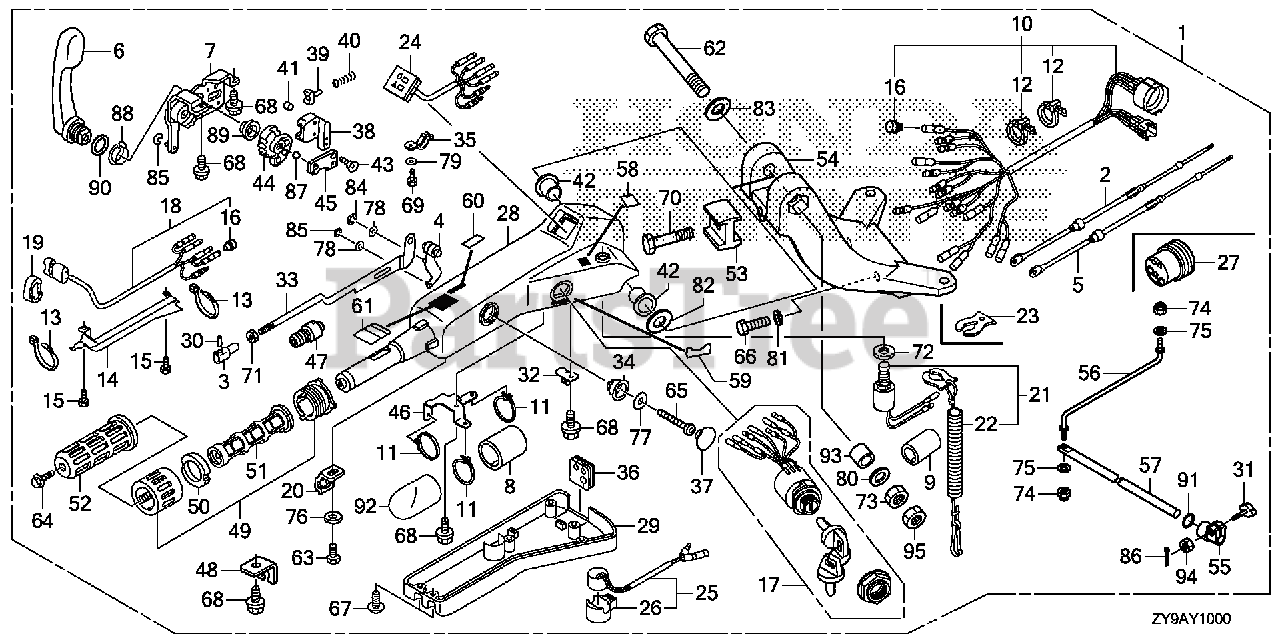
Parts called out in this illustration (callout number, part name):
1	HANDLEBAR KIT *NHB14M* (AQUA MARINE SILVER METALLIC)
2	CABLE, THROTTLE
3	PIVOT, THROTTLE CABLE
4	ARM, THROTTLE
5	CABLE, SHIFT
6	LEVER, SHIFT
7	FRAME ASSY., SHIFT
8	TUBE (38.1X40)
9	TUBE
10	CABLE ASSY., LONG HANDLE (A)
11	BAND (CONVEX CV-150)
12	BAND (CONVEX CV-200)
13	BAND (CONVEX)
14	COVER, WIRE
15	SCREW
16	PLUG, CONNECTOR (INNER)
17	SWITCH ASSY., COMBINATION
18	SWITCH ASSY., POWER TILT
19	GROMMET
20	HOLDER, SWITCH
21	SWITCH ASSY., EMERGENCY STOP
22	WIRE, EMERGENCY
23	CLIP, EMERGENCY LOCK
24	LAMP ASSY., INDICATOR
25	BUZZER ASSY., WARNING
26	SUSPENSION, WARNING BUZZER
27	GROMMET, HANDLEBAR CABLE
28	HOUSING *NHB14M* (AQUA MARINE SILVER METALLIC)
29	COVER, HANDLEBAR (LOWER)
30	PIN, THROTTLE CABLE
31	BOLT, FRICTION
32	BRACKET, CABLE
33	PLATE ASSY., LOCK
34	STOPPER
35	PLATE, GUIDE
36	GROMMET
37	CAP
38	GUIDE, SPRING
39	ACTUATOR
40	SPRING, COIL
41	ROLLER
42	BUSH, HANDLEBAR
43	SCREW (M5X14)
44	GEAR, SHIFT
45	PLATE, BALL GUIDE
46	BRACKET
47	ROD, GROMMET
48	CLAMP, BRACKET
49	GRIP ASSY., THROTTLE FRICTION
50	PAD, THROTTLE FRICTION
51	PIPE, GRIP
52	RUBBER, GRIP
53	BLOCK, HEIGHT ADJUSTER
54	BRACKET B, STEERING *NHB14M* (AQUA MARINE SILVER METALLIC)
55	BLOCK, STEERING FRICTION
56	ROD, STEERING FRICTION
57	SHAFT, STEERING FRICTION
58	MARK, EMERGENCY SWITCH INDICATION (EU)
59	MARK, STARTER (ENGLISH)
60	MARK, CHANGE
61	MARK, THROTTLE (ENGLISH)
62	BOLT, HEX. (12X80)
63	BOLT (M5X8)
64	BOLT, FLANGE (6X12)
65	BOLT (M8X50)
66	BOLT, HEX. (10X32)
67	BOLT (M5X12)
68	BOLT (M6X12)
69	BOLT (M5X12)
70	BOLT, FLANGE (8X28)
71	NUT, HEX. (5MM)
72	NUT, HEX. (16MM)
73	NUT, HEX. (12MM)
74	NUT, SELF-LOCK (8MM)
75	WASHER, PLAIN (8MM)
76	WASHER (5MM)
77	WASHER (8MM)
78	WASHER (10MM)
79	WASHER (5MM)
80	WASHER, WAVE (14MM)
81	WASHER (10MM)
82	WASHER, PLAIN (12MM)
83	WASHER, PLAIN (12MM)
84	E-RING
85	E-RING
86	PIN, SPLIT (2.0)
87	BALL, STEEL
88	BEARING
89	BEARING
90	O-RING (20.6X1.9)
91	O-RING (15.54X2.62)
92	TUBE, CORD (40MM)
93	COLLAR, DISTANCE (12.2X23X16)
94	NUT, HEX. (6MM)
95	NUT, HEX. (12MM)
